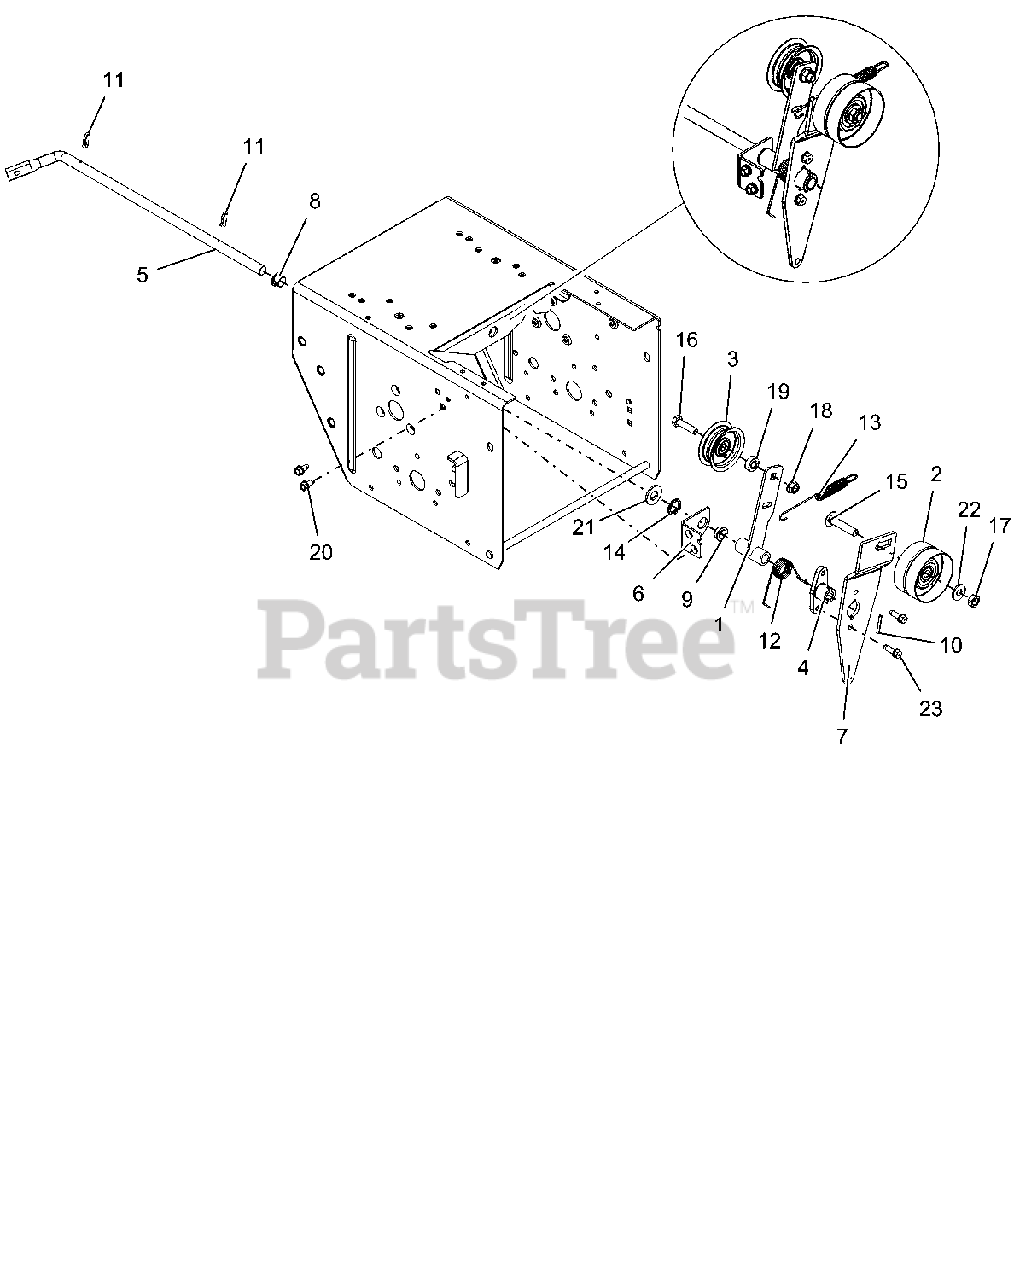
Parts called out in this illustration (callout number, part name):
1	ARM, IDLER-TRACTION
2	IDLER, FLAT-2.75 OD X .375 ID
3	IDLER, FLAT - 2.00"
4	HUB, BRAKE ARM
5	ARM, ATTACHMENT
6	BRACKET, SUPPORT
7	ARM, IDLER-ATTACHMENT
8	BUSHING, POLYLINER-.50 SPLIT
9	BSHG,FLANGE .500X.625X.270X.75
10	PIN-ROLL .125X1.00
11	CLIP, SPRING
12	SG-TORS .067X.88
13	SG-TENS .06X.482X5.35
14	WAVE SPRING .600X.875X.25FH
15	@BLT-RHDSSQNK .38-16X1.75 G5YZ
16	@BLT-HEX .31-18X1.25 GR5 YWZC
17	@NUT-LK-CTR-JAM .375-16 YWZC
18	@NUT-LK-TOP-FLG .31-18 YWZC
19	SPCR, BRG .315X.500X.358X.281
20	SCR-TAP .25-20X.50 HWH TR YWZ
21	@WSHR-FL-STL.531X1.06X.095YWZC
22	@WSHR-FL-STL.38X.875X.083 YWZC
23	SCR-TAP-PM .25-20X.75 TR YWZ
